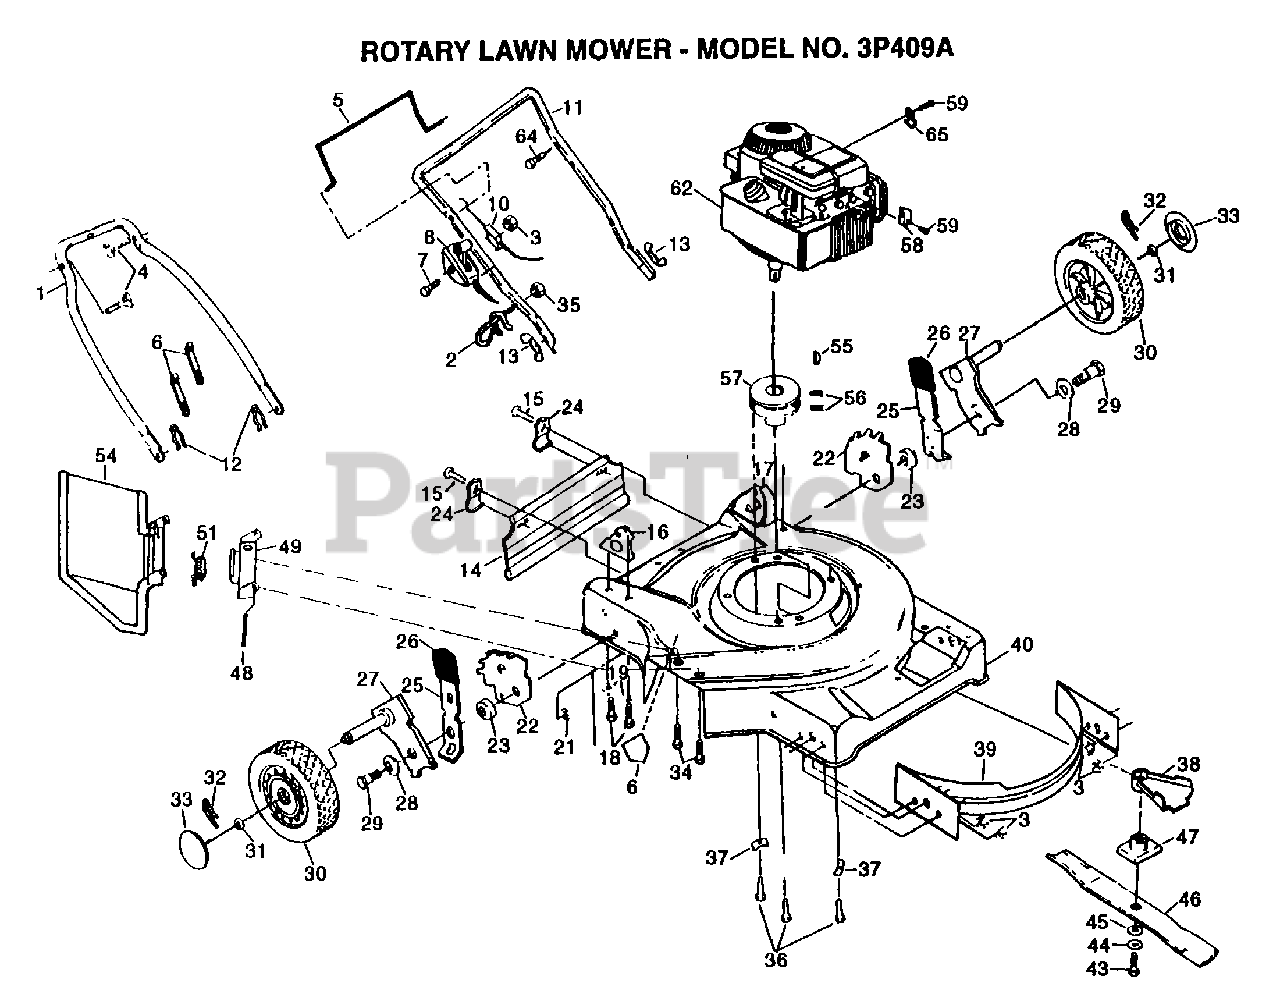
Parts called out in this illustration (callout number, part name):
2	ROPE GUIDE
4	BOLT.HANDLE.LM
5	CONTROL BAR
7	SCREW.HXHD.WASH.
8	CONTROL THROTTLE
10	"CABLE,ENG ZONE CO"
12	HAIRPIN COTTER
13	"NUT,WING PM"
14	SKIRT.REAR.FGD.22
15	TAPPING SCREW
18	SCREW
19	STEEL WASHER
21	LOCKNUT PM
22	BRACKET.ADJ.9POS.
24	"BRKT,DEFL PM"
25	SPRING SELECTOR
26	KNOB PM
27	AXLE ARM
28	"WASHER, BELLEVIL."
29	BOLT SHLD 3/8-16
31	WASHER
32	RETAINER CLIP PM
33	HUB CAP
35	NUT
36	SCREW
39	BAFFLE FRONT 22SD
40	KIT.HSG.22SD.FWGD
43	SCREW
44	LOCKWASHER
45	"WASHER,HARDEN"
46	"BLADE.MULCH.22"""
47	ADAPTOR.BLADE.LM
48	ROD.HINGE.COMBI-C
49	BRACKET.HINGE.W/F
54	GUARD.DISCH.22SD.
55	HI PRO KEY PM
56	SCREW
57	ENGINE.PULLEY.FWG
58	CABLE CLAMP
59	SCREW PM
61	DECAL HYT
64	"SCREW,PAN HD"
65	GUIDE CLIP PM
